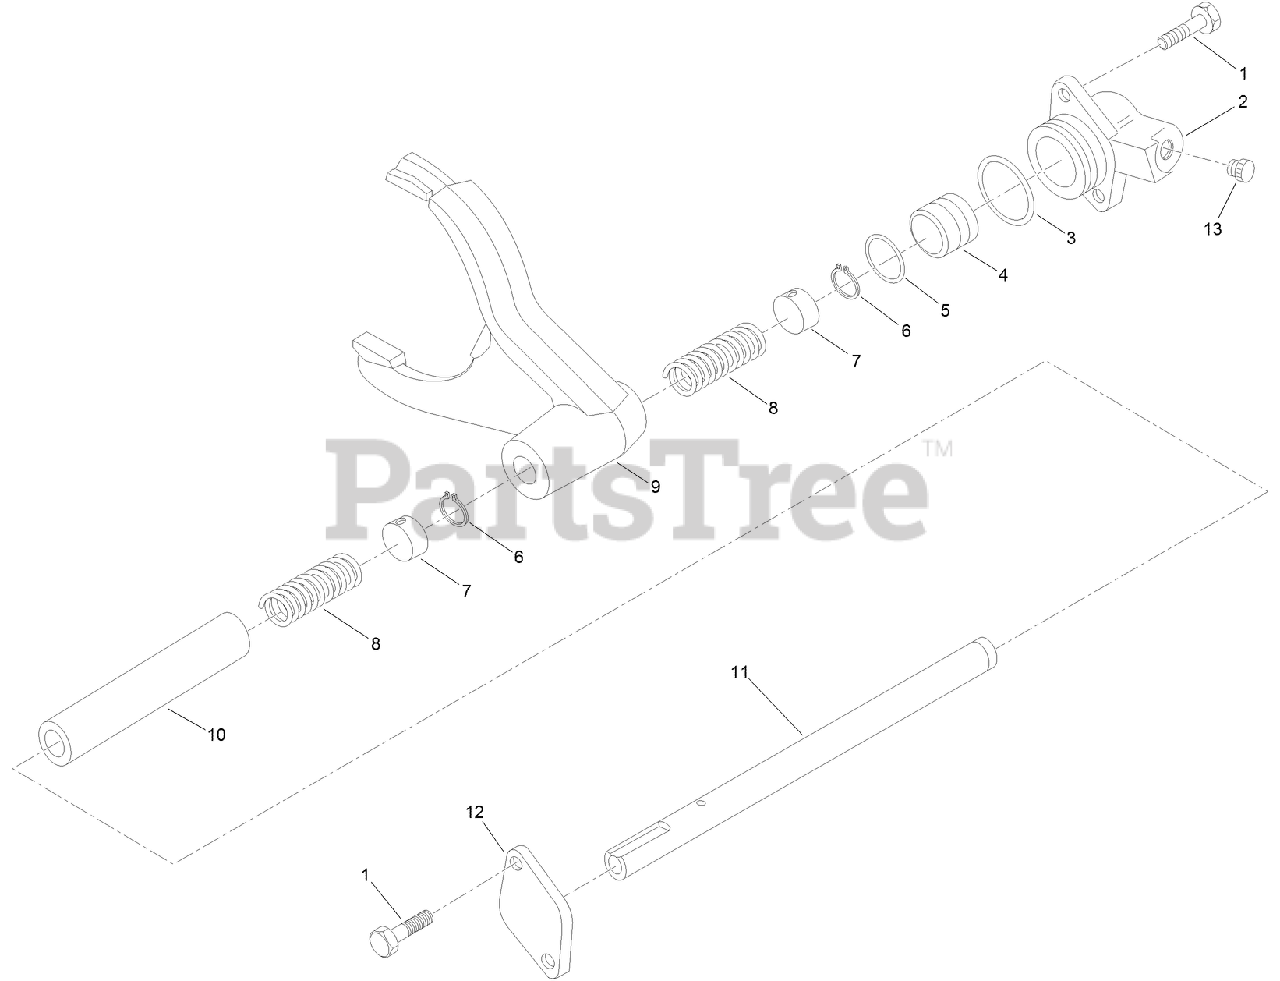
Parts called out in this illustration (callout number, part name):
2	SUPPORT-CYLINDER
3	O-RING
4	PISTON
5	O-RING
6	RING-SNAP
7	SPACER
8	SPRING
11	SHAFT-DRIVE
12	FLANGE
